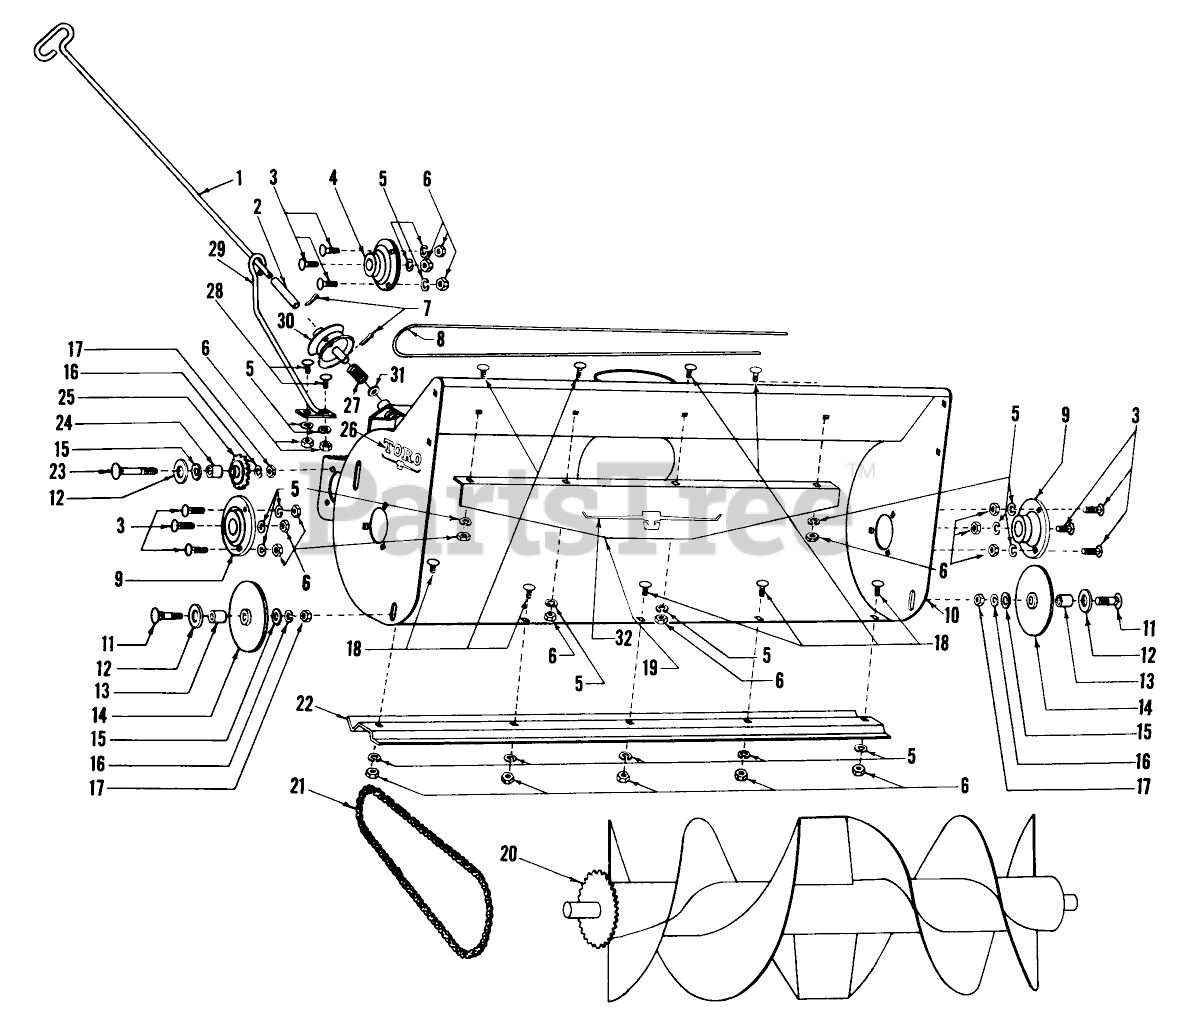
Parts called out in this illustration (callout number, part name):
1	Rod Chute Handle
2	Sleeve
3	Carriage Bolt
4	Bearing w/Setscrew
7	Cotter Pin
8	Control Cable
9	Bearing w/Setscrew
10	Housing
11	Carriage Bolt
13	Bushing
14	Guide Wheel
16	Washer
18	Carriage Bolt
19	Snow Shield
20	Rotor Assembly
21	Roller Chain
22	Blade-Scraper
23	Carriage Bolt
24	Spacer
25	Chain Idler
26	Decal
27	Compression Spring
28	Carriage Bolt
29	Chute Handle Support
30	Chute Control
31	Washer
32	Decal
